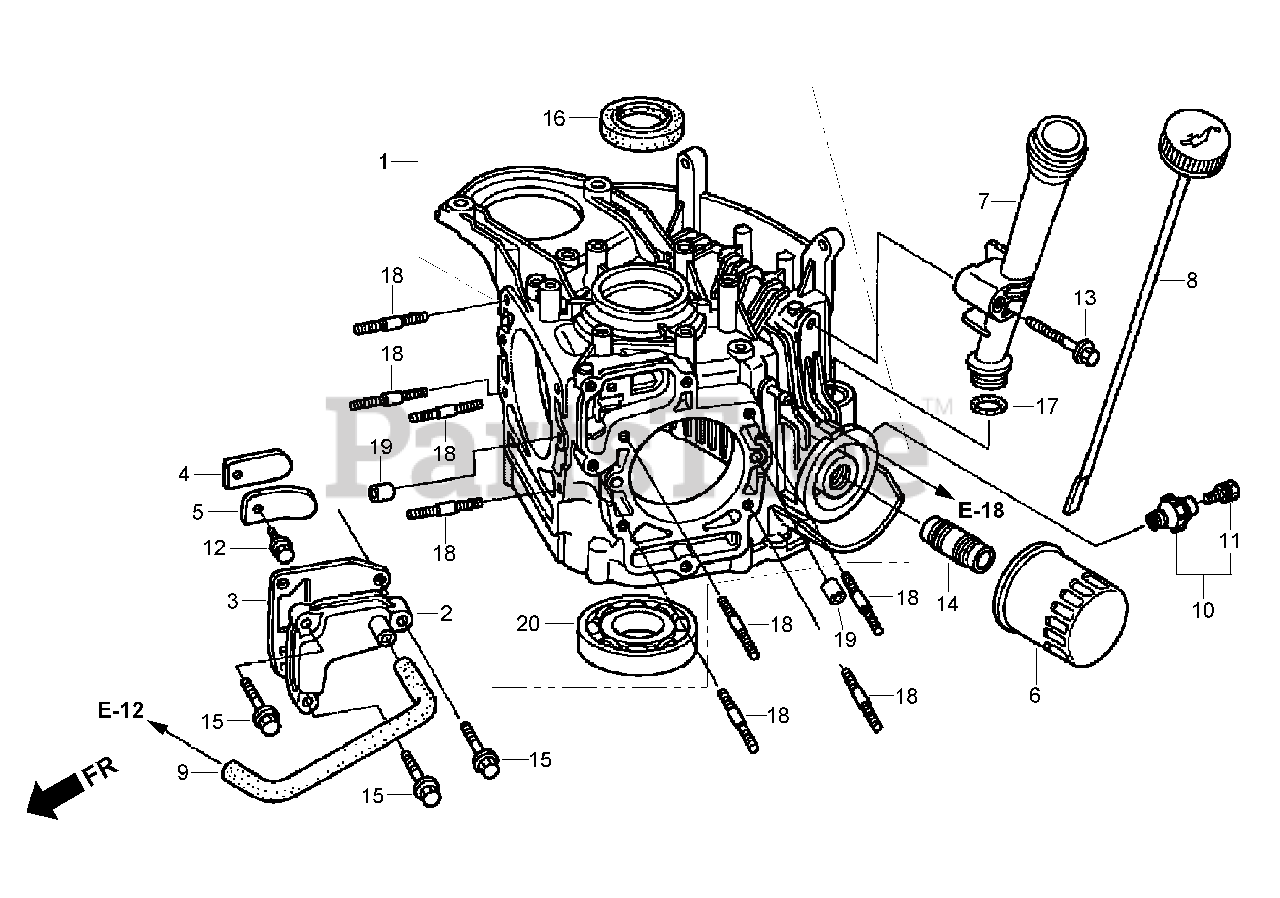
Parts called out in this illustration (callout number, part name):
1	CRANKCASE ASM (840)
2	COVER-BREATHER
3	GASKET-COVER, BREATHER
4	PLATE-VALVE
5	STOPPER-VALVE
6	FILTER-OIL (TOYO ROKI) ( Up To Engine Serial No. 1006029)
6	FILTER, OIL (TOYO ROKI)
7	EXTENSION-FILLER, OIL
8	DIPSTICK-OIL
9	TUBE-BREATHER
10	OIL PRESSURE SWITCH ASM
11	BOLT-WASHER (4X8) (DENSO)
12	BOLT-FLANGE (5X10)
13	BOLT-FLANGE (6X45) (C T200)
14	HOLDER-FILTER, OIL
15	BOLT-FLANGE (6X25) (C T 200)
16	SEAL-OIL (35X5X8)
17	O-Ring (22.5X2.2)
18	BOLT-STUD (8X28)
19	Pin-Dowel (8X14)
20	BEARING-BALL, RADIAL
